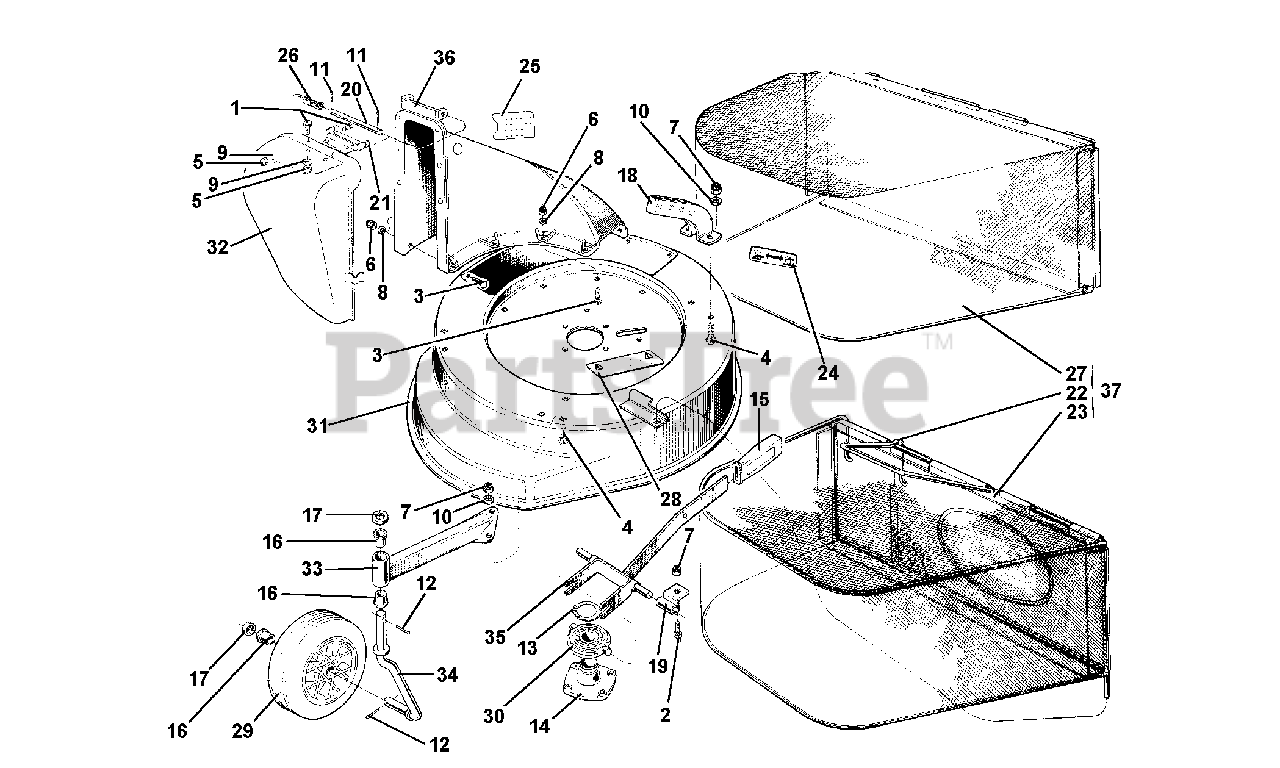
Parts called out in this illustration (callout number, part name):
1	SCREW M5 X 10
2	SCREW M8 X 16
3	SCREW M6 X 20
4	SCREW TTQ M8 X 20 UNI 5731
6	NUT, SELF LOCKING M6
7	NUT, SELF LOCKING M8
8	WASHER, FLAT 6.4
9	SUPER WASHER
10	WASHER, LOCK 8.4
11	COTTER PIN A 3 X 15 UNI 1336 AC.
12	PIN, COTTER 4 X 25
13	CIRCLIP, EXT. D 35
14	BLADE HOLDER HUB
18	CUTTING HEIGHT SELECTOR
24	TRANSFER FOR LAWN MOWER
26	DEFLECTOR SPRING
29	SMALL WHEEL
31	LAWN MOWER CRANCASE
33	WHEEL SUPPORT
35	ADJUSTING LEVER
37	CATCHER COMPLETE
